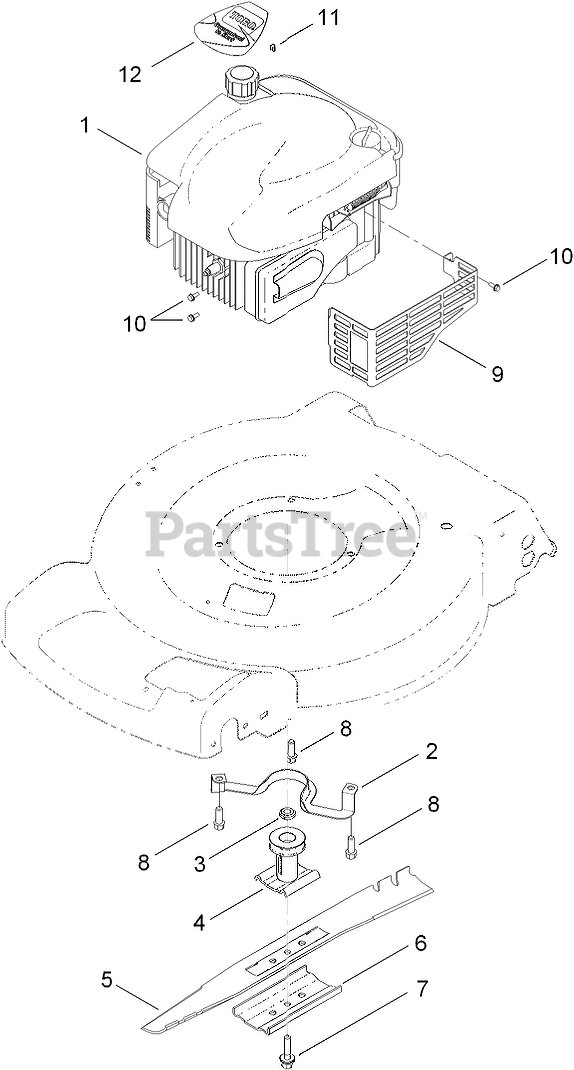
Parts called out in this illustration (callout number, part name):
2	Guide-Belt
3	Spacer-Driver
4	DRIVER-BLADE
5	BLADE
6	SUPPORT-BLADE
7	BOLT-BLADE
8	SCREW-TAPTITE
9	SHIELD-MUFFLER
10	SCREW-TAPTITE
11	STOP-ROPE
12	DECAL-SHROUD
